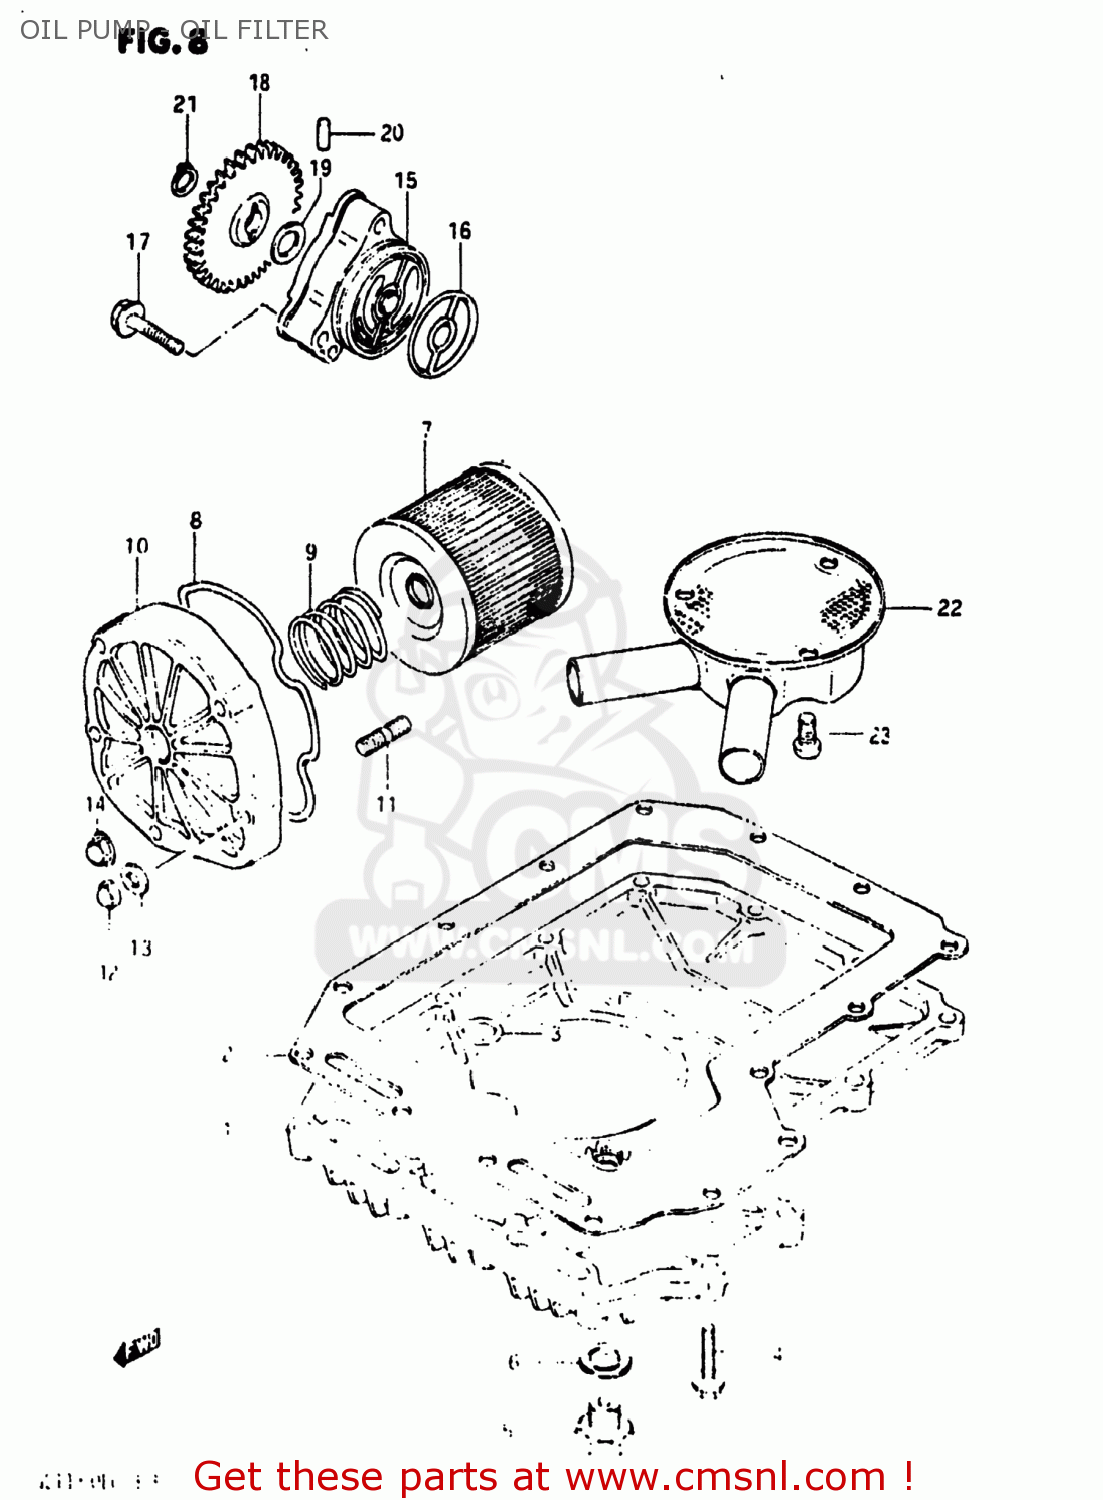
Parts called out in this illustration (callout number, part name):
1	PAN,OIL
2	GASKET,OIL PAN (MCA)
3	O RING(D:3.2,ID:12.9)
4	BOLT
5	PLUG
6	GASKET(14X19.2X2) (NAS)
7	FILTER ASSY,ENGINE OIL
8	O RING,OIL FILTER CHAMBER CAP
9	SPRING
10	CAP,ENGINE OIL FILTER
11	STUD 6X25
12	NUT 6MM
13	WASHER
14	NUT
15	PUMP ASSY,ENGINE OIL
16	O RING,OIL PUMP
17	BOLT(6X32)
18	GEAR,ENG OIL PUMP DRIVEN(NT:33
19	SHIM
20	PIN(4X15.8)
21	CIRCLIP
22	STRAINER,ENGINE OIL
23	SCREW 6X12
